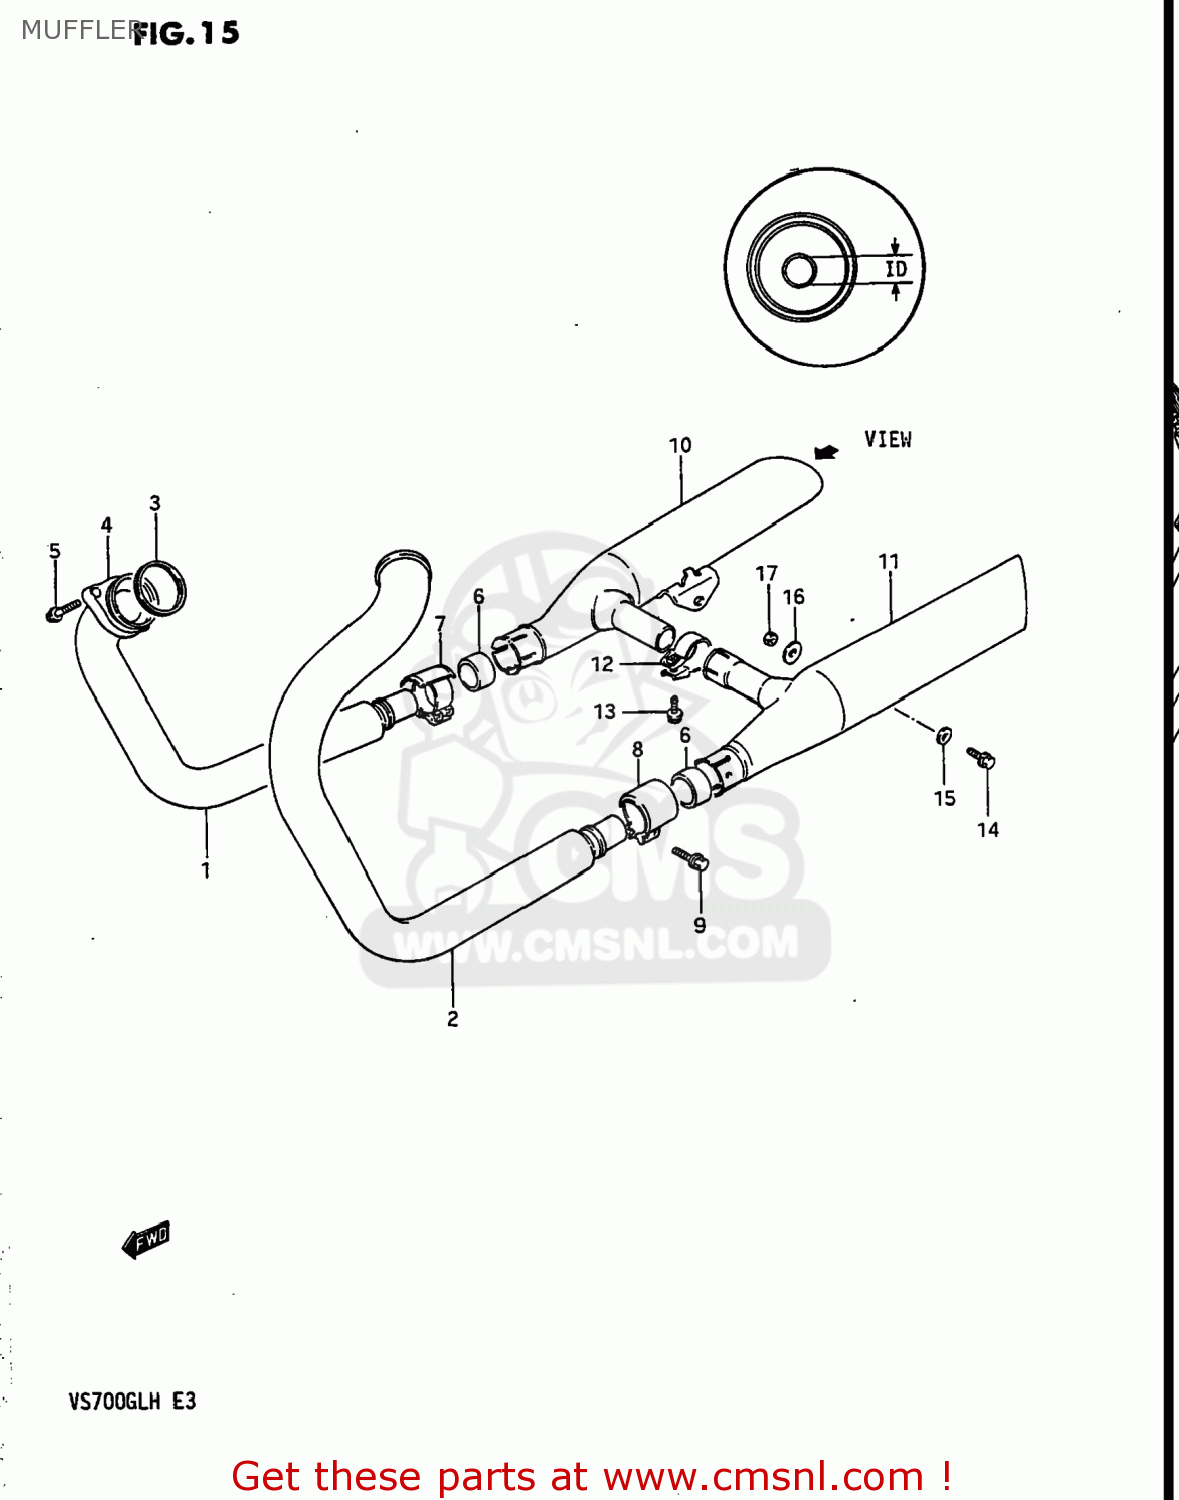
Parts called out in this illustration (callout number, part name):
1	PIPE,EXHAUST
2	PIPE,EXHAUST
3	GASKET,EXHAUST PIPE (NAS)
4	CLAMP,EXHAUST PIPE
5	BOLT(8X35)
6	CONNECTOR,MUFFLER
7	CLAMP,MUFFLER CONNECTOR,R
8	CLAMP,MUFFLER CONNECTOR,L
9	BOLT
10	BODY,MUFFLER
11	BODY,MUFFLER
12	CLAMP,EXHAUST
13	BOLT
14	BOLT
15	WASHER
16	WASHER
17	NUT
